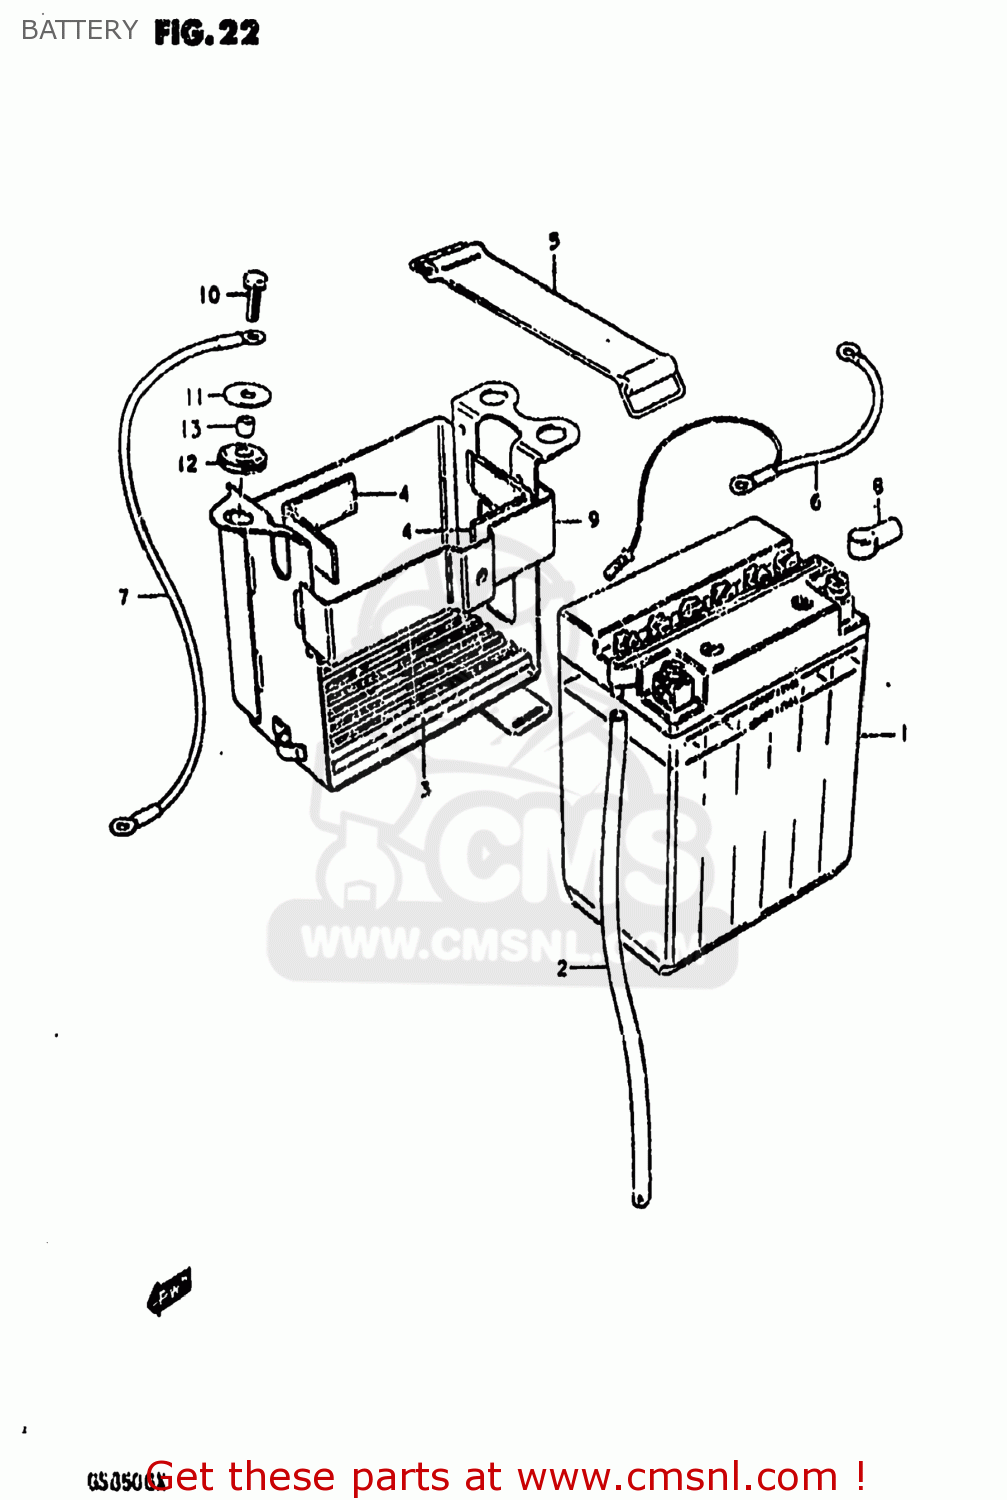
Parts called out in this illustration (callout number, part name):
1	BATTERY ASSY (12V)
2	HOSE,BATTERY EXHAUST
3	PROTECTOR,BATTERY
4	PROTECTOR(20X90)X4
5	BAND
6	WIRE,BATTERY PLUS
7	LEAD WIRE,BATTERY(-)
8	CAP,TERMINAL
9	HOLDER,BATTERY
10	BOLT, UPPER
11	WASHER(6,5X22X1.6)
12	CUSHION
13	SPACER(6.2X8.3X5.7)
